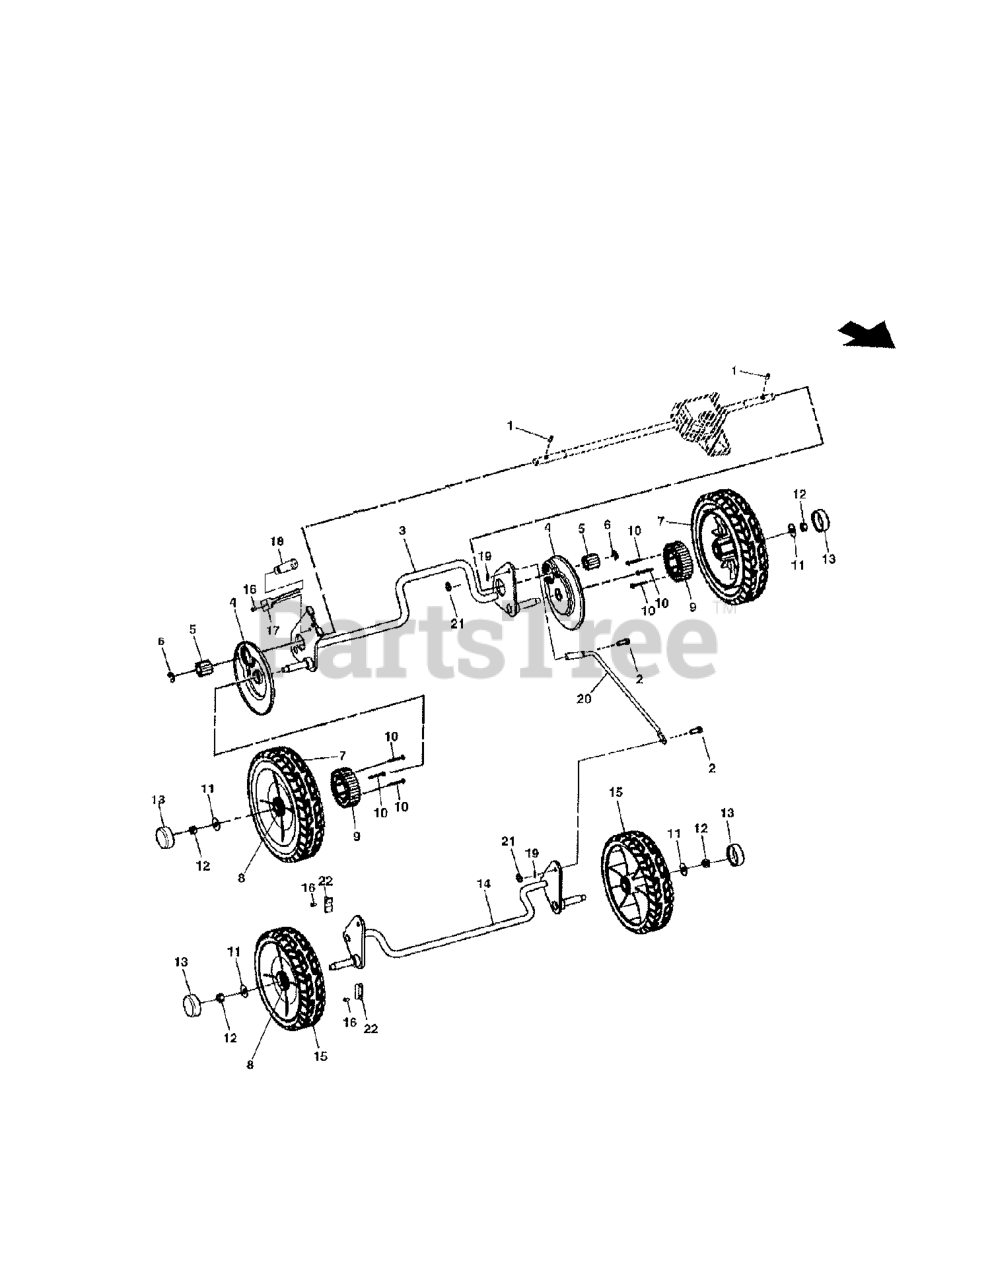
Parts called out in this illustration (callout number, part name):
1	PIN, AXLE
2	BOLT, SHOULDER, 1/4 X .375, YZ
3	WELDMENT, REAR CROSSBAR 21" WBM, RD, YZ
4	SHIELD, DUST, 21" WBM, RD
5	GEAR, PINION
6	RETAINING RING
7	ASSY, WHEEL, W/BEARING 9" JD TRD, JD YELLOW
8	BEARING, BALL, 1-1/8"OD, FLANGE
9	GEAR, EXTERNAL WHEEL
10	HWST, #8 X 1-1/4, HI-LO
11	WASHER, FLAT, 1" OD X .387 ID
12	HCLN, 3/8-16 YZ
13	HUBCAP, ROUND, JD YELLOW
14	WELDMENT, FRONT CROSSBAR 21" WBM, RD, YZ
15	ASSY, WHEEL, 8X2 IDLE, JD TRD, BB, JD YELLOW
16	TORX ST, 1/4-20 X .550
17	LEVER, SPRING HOC
18	GRIP HOC
19	PUSHNUT, 1/4 BLK
20	ROD, LIFTER LINK, 21" WBM, RD
21	HLN, 10-24 UNC-2B W/NYLON INSERT
22	BUSHING, FRONT 21"
